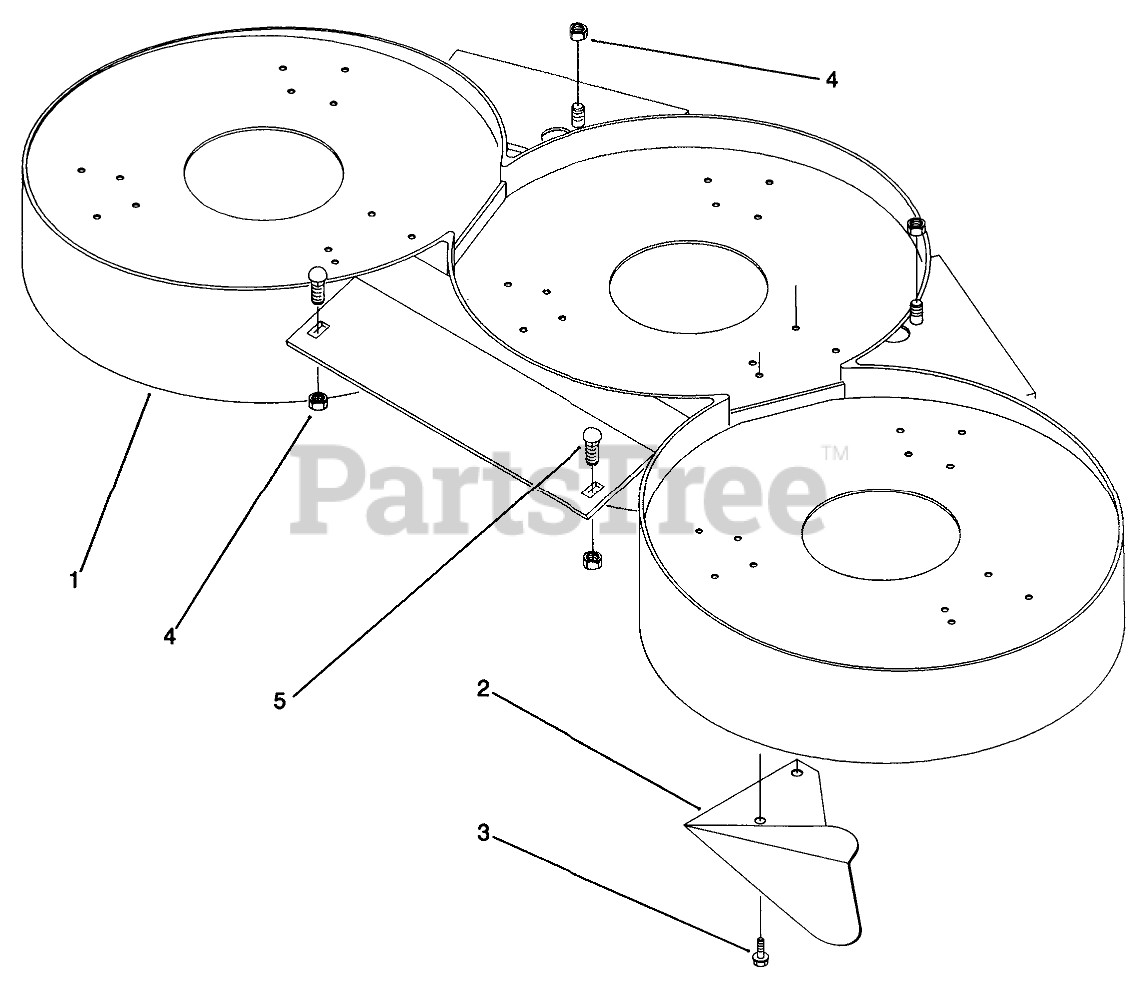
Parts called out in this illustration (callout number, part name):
1	Baffle
2	Kicker
3	Bolt
4	NUT
5	Bolt
